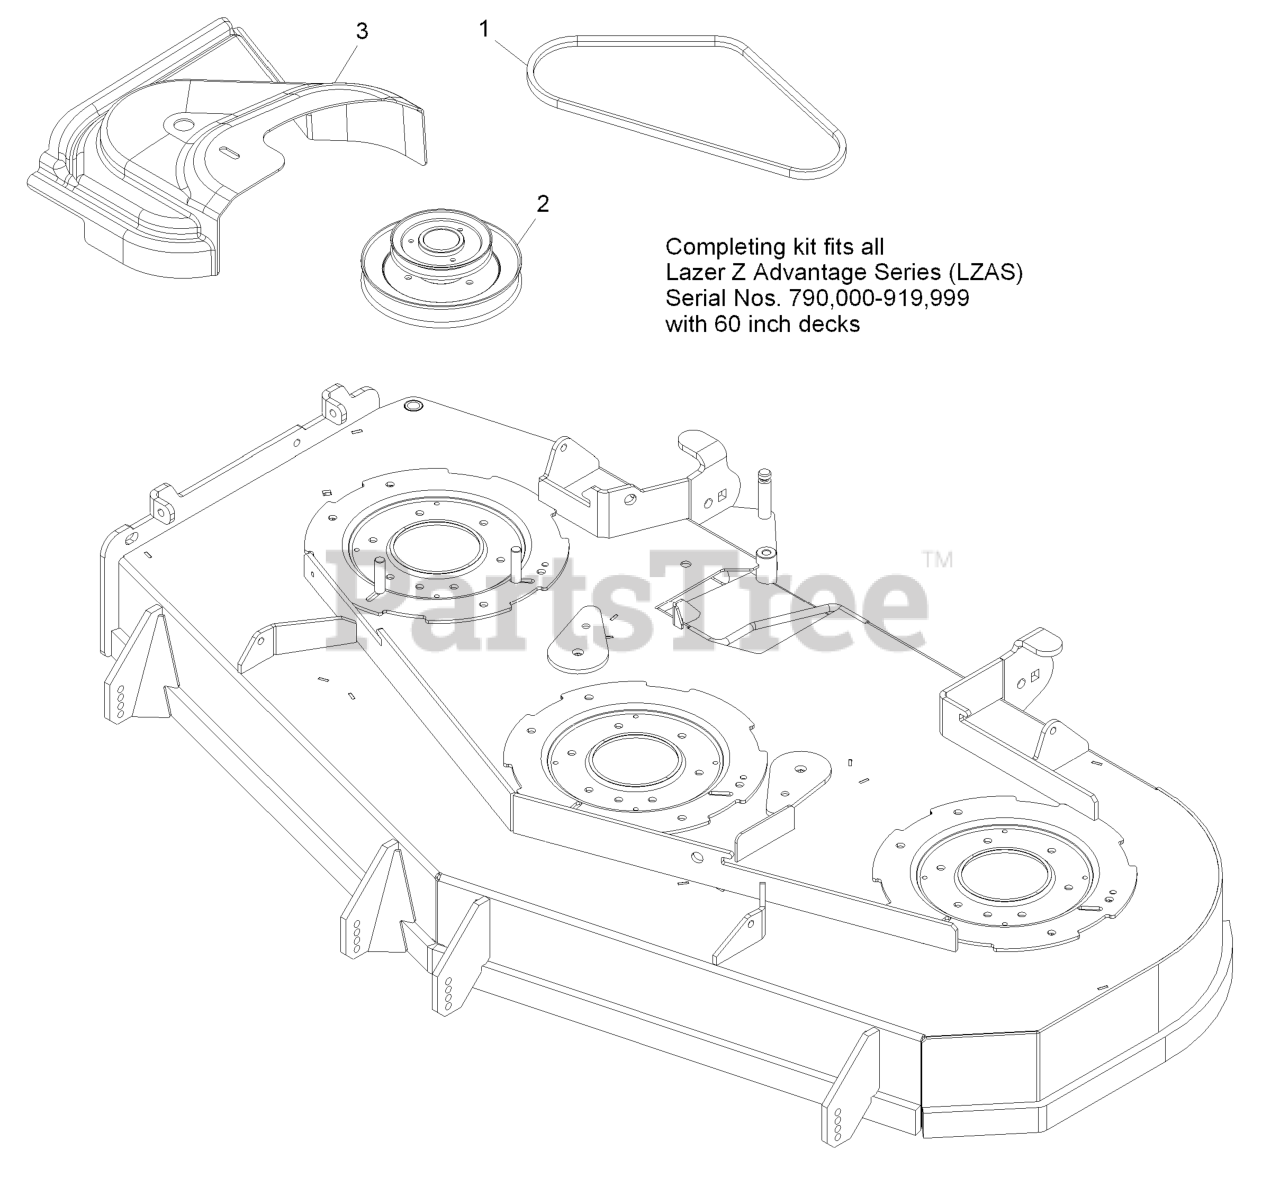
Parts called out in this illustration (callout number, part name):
1	Belt, Blower Drive 60
2	Jackshaft,Uv Drive 604
3	Cover,Belt Uv 60
